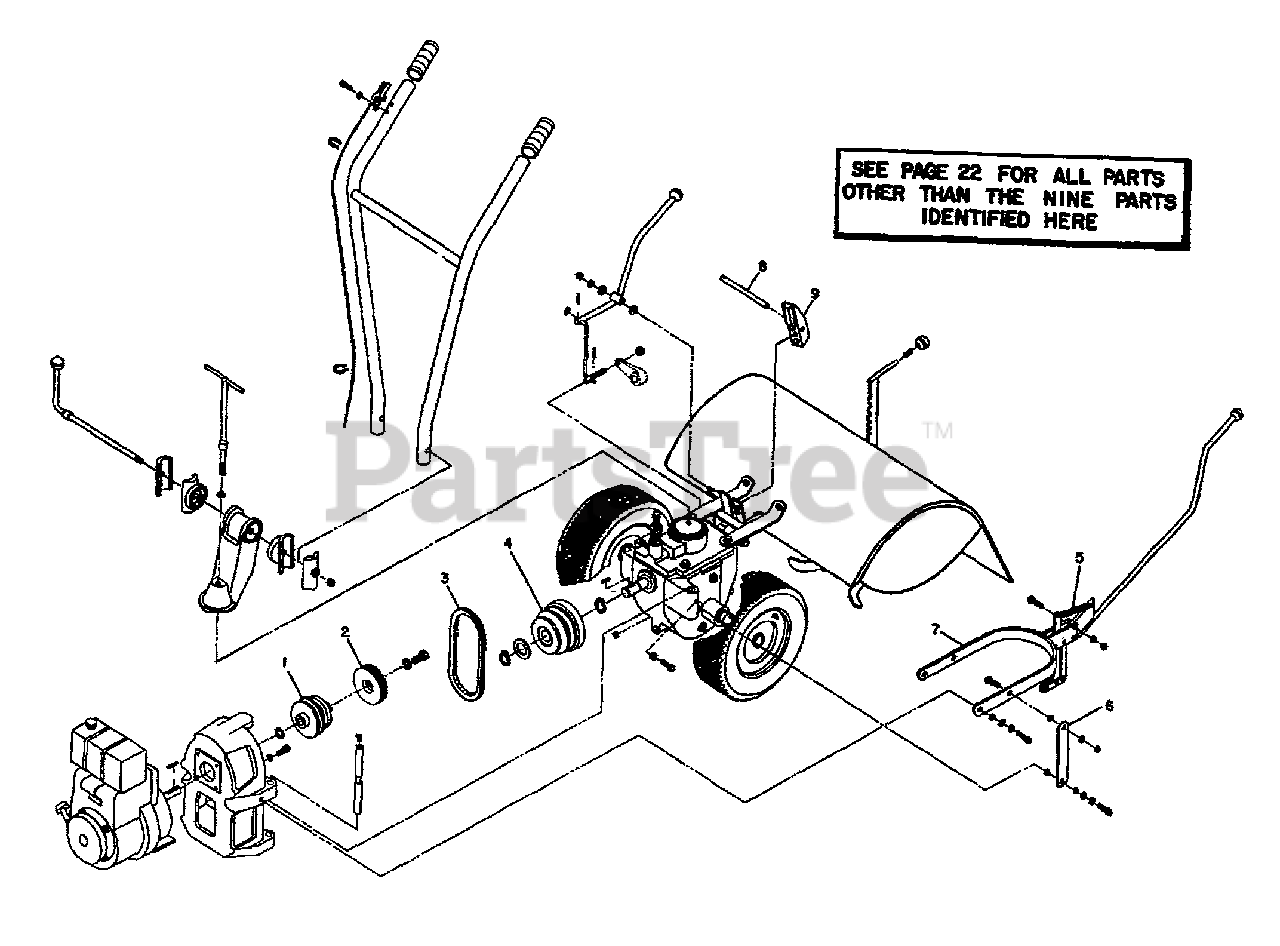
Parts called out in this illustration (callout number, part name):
1	PULLEY-ENG MACH
2	KIT-ADJ BLOCK/REV DISC
3	BELT-V
4	PULLEY-TRANS-MACH
5	SPRING-.436 X 3.25
6	BAR-CLUTCH YOKE
7	KIT-LEVER FWD/REV-HORSE 2
8	BAR-ADJUST
9	KIT-ADJ BLOCK 4 SP
